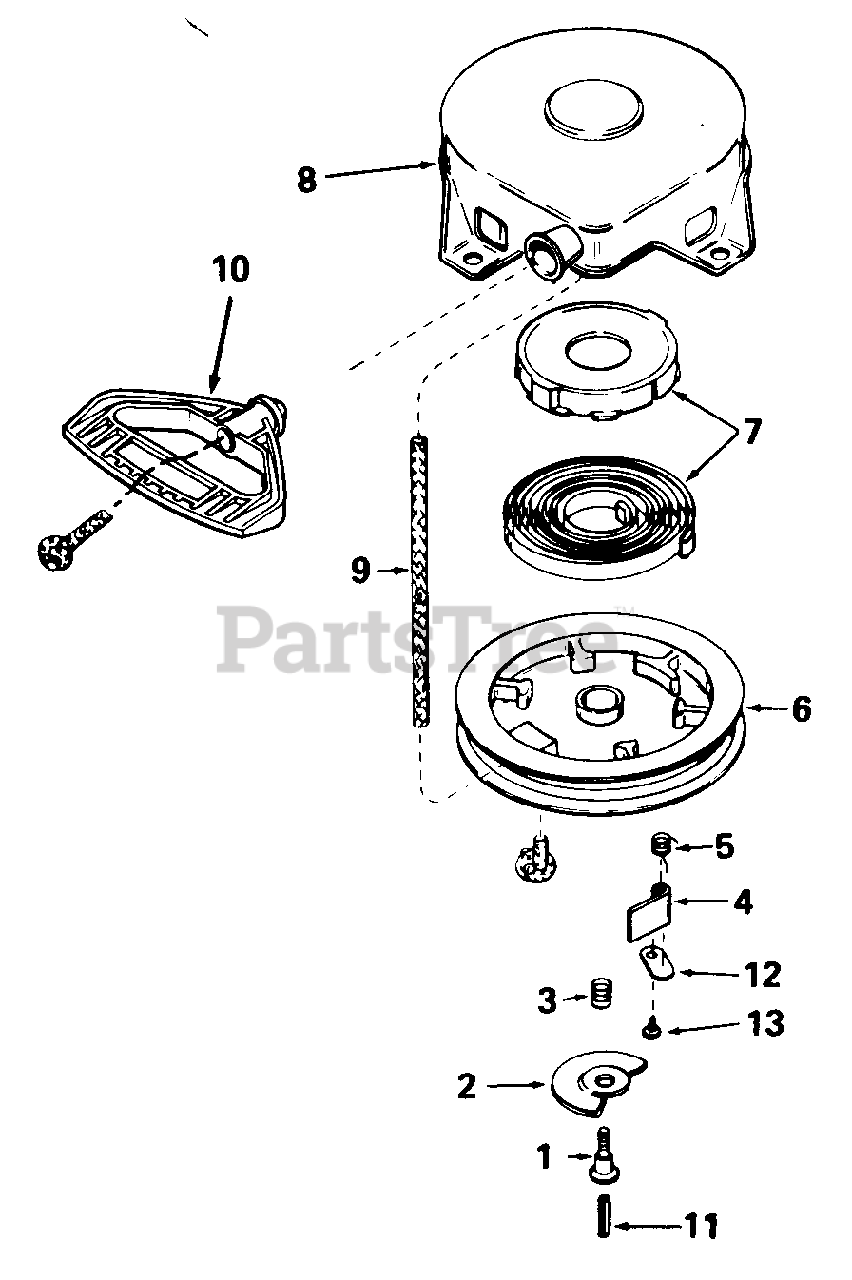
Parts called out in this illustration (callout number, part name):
1	Screw, Retainer
3	Spring, Brake
4	Dog, Starter
5	Spring, Dog
7	Spring & Keeper Ass'y.
8	Housing Ass'y., Starter
9	Rope, Starter
10	Handle, Mitten Grip
11	Pin, Centering
12	Retainer, Dog
13	Screw, No. 6 x 5/16
